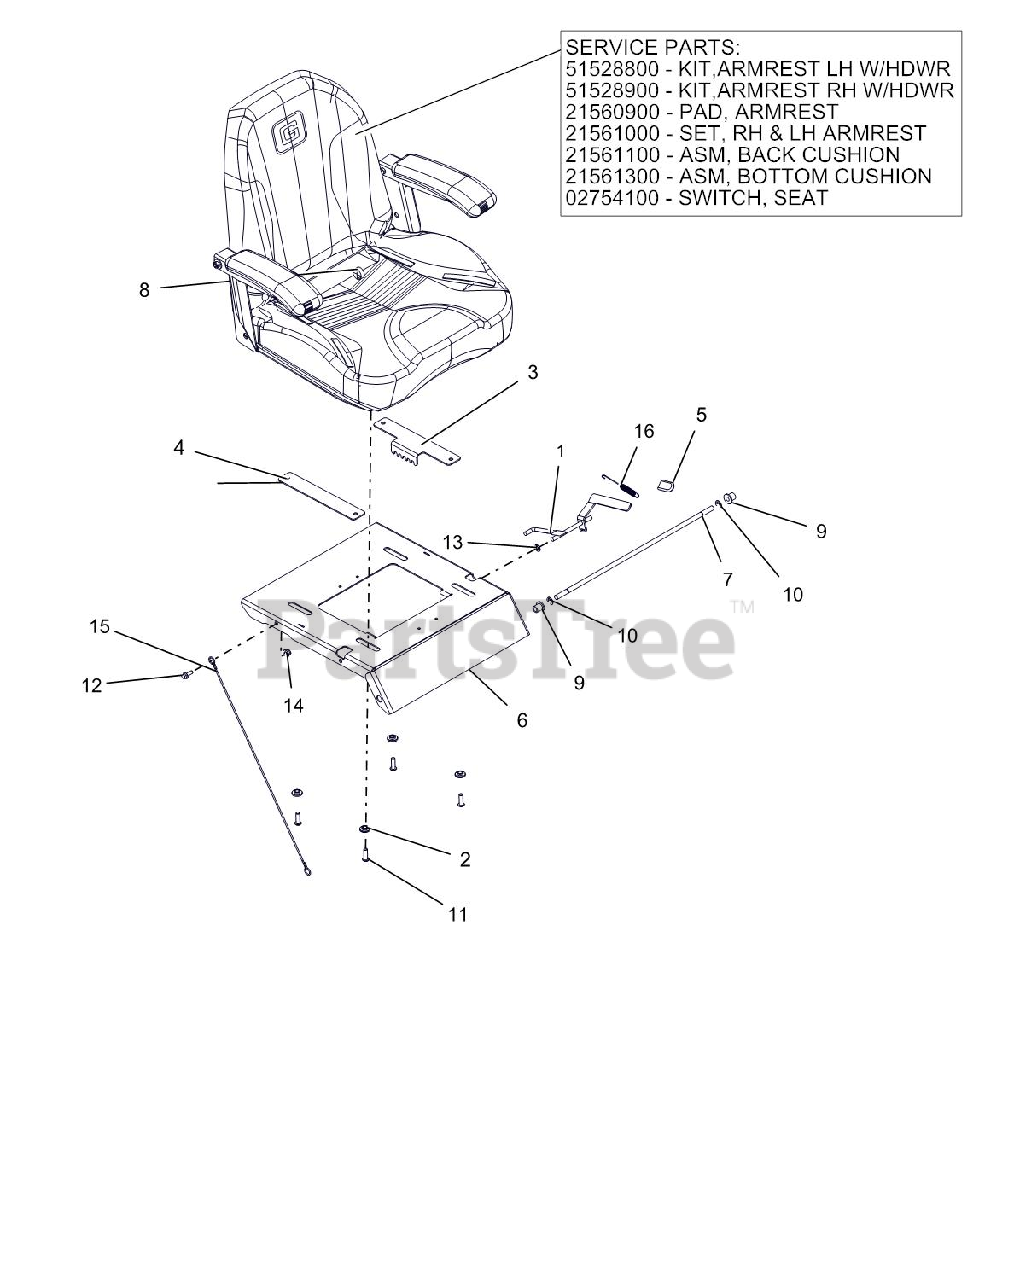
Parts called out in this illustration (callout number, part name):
1	WLDMT, ADJUSTABLE SEAT LATCH
2	BSHG, FLG .325X.499X.26X.88
3	PLATE, ADJUSTABLE SEAT TRACK
4	PLATE, ADJUSTABLE SEAT SLIDE
5	GRIP, SEAT LEVER, GREY
6	PLATE, SEAT
7	ROD, SEAT PIVOT
8	SWITCH- SNAP MTG N.O.
8	KIT, ARMREST LH
8	KIT, ARMREST RH
8	SEAT, ZTX 2017
8	PAD, ARMREST (HARD)
8	SET,RH & LH ARMREST -HARD
8	ASM,BACK CUSHION-GRAVELY X
8	ASM,BOTTOM CUSHION-GRAVELY X
9	BSHG-FLG .38X.580X.667X.750
10	RG-RTNG-EXT .375X.035 TYP E
11	SCR-SKH .31-18X1.0 BTNHD YWZC
12	BLT,HEX-FLG .25-20X.75 G5 BFP
13	NUT-PUSH .312
14	@NUT-LK-NYL-FLG .31-18 YWZC
15	LANYARD, SEAT CABLE .093X19.5
16	SG-TENS .043X.44X3.31 WLD 5.8
